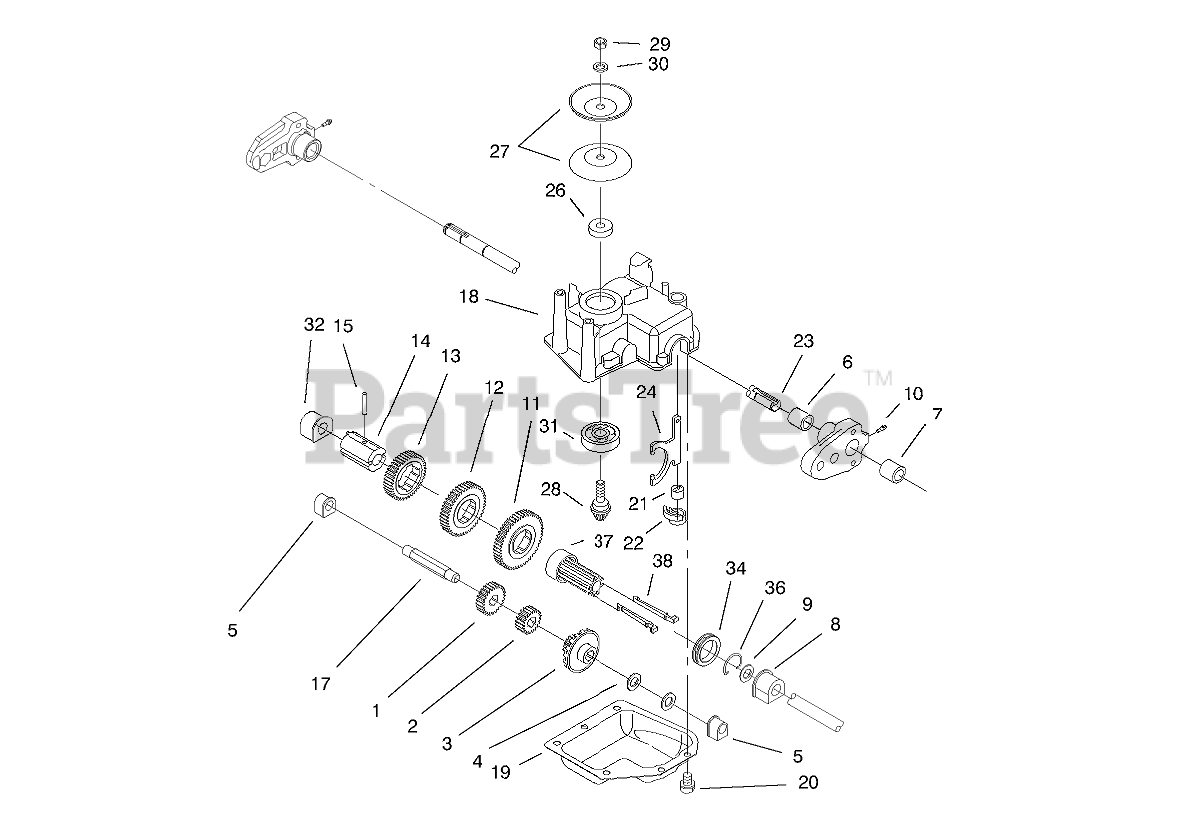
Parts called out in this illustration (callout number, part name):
1	PINION-25T
2	PINION-20T
3	Gear-Bevel
4	WASHER-THRUST
5	BUSHING
6	BUSHING
7	BEARING-ROLLER
8	BUSHING-OUTPUT
9	WASHER-PLAIN
10	FITTING-GREASE
11	GEAR-49T
12	GEAR-44T
13	GEAR-39T
14	SLEEVE-GEAR
15	PIN-SPRING
17	SHAFT-INTERMEDIATE
18	CASE-GEAR, UPPER
19	Cover-Gearcase
20	SCREW-HWHTF
21	BUSHING-YOKE
22	RETAINER-FORK, SHIFT
23	SHAFT-OUTPUT
24	YOKE-SHIFT
26	SPACER
27	Pulley Half
28	Gear-Pinion
29	NUT-HEX
30	WASHER-FLAT
31	BEARING-BALL
32	BUSHING
34	COLLAR-SHIFT
36	CLIP-SPRING
37	SLEEVE-KEY, SHIFT
38	KEY-SHIFT
